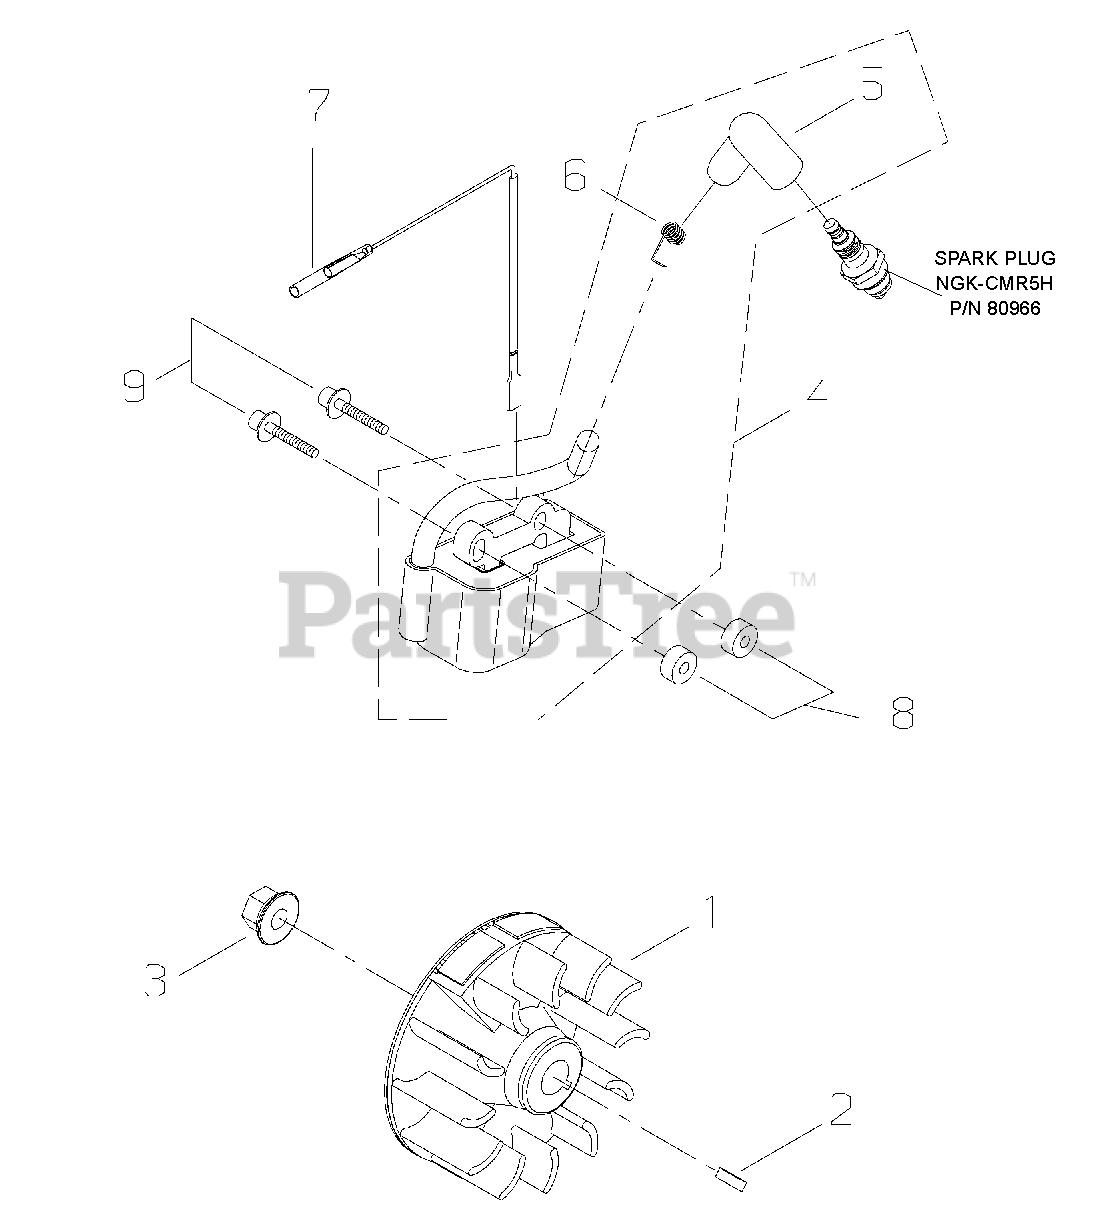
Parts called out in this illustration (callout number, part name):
2	KEY, WOODRUFF 3×10
3	NUT M8
4	IGNITION COIL ASSY
5	CAP, SPARK PLUG
6	TERMINAL, SPARK PLUG
7	LEAD - IGNITION L= 220 MM
8	INSULATOR 4.2×11×6
9	BOLT M4×26
